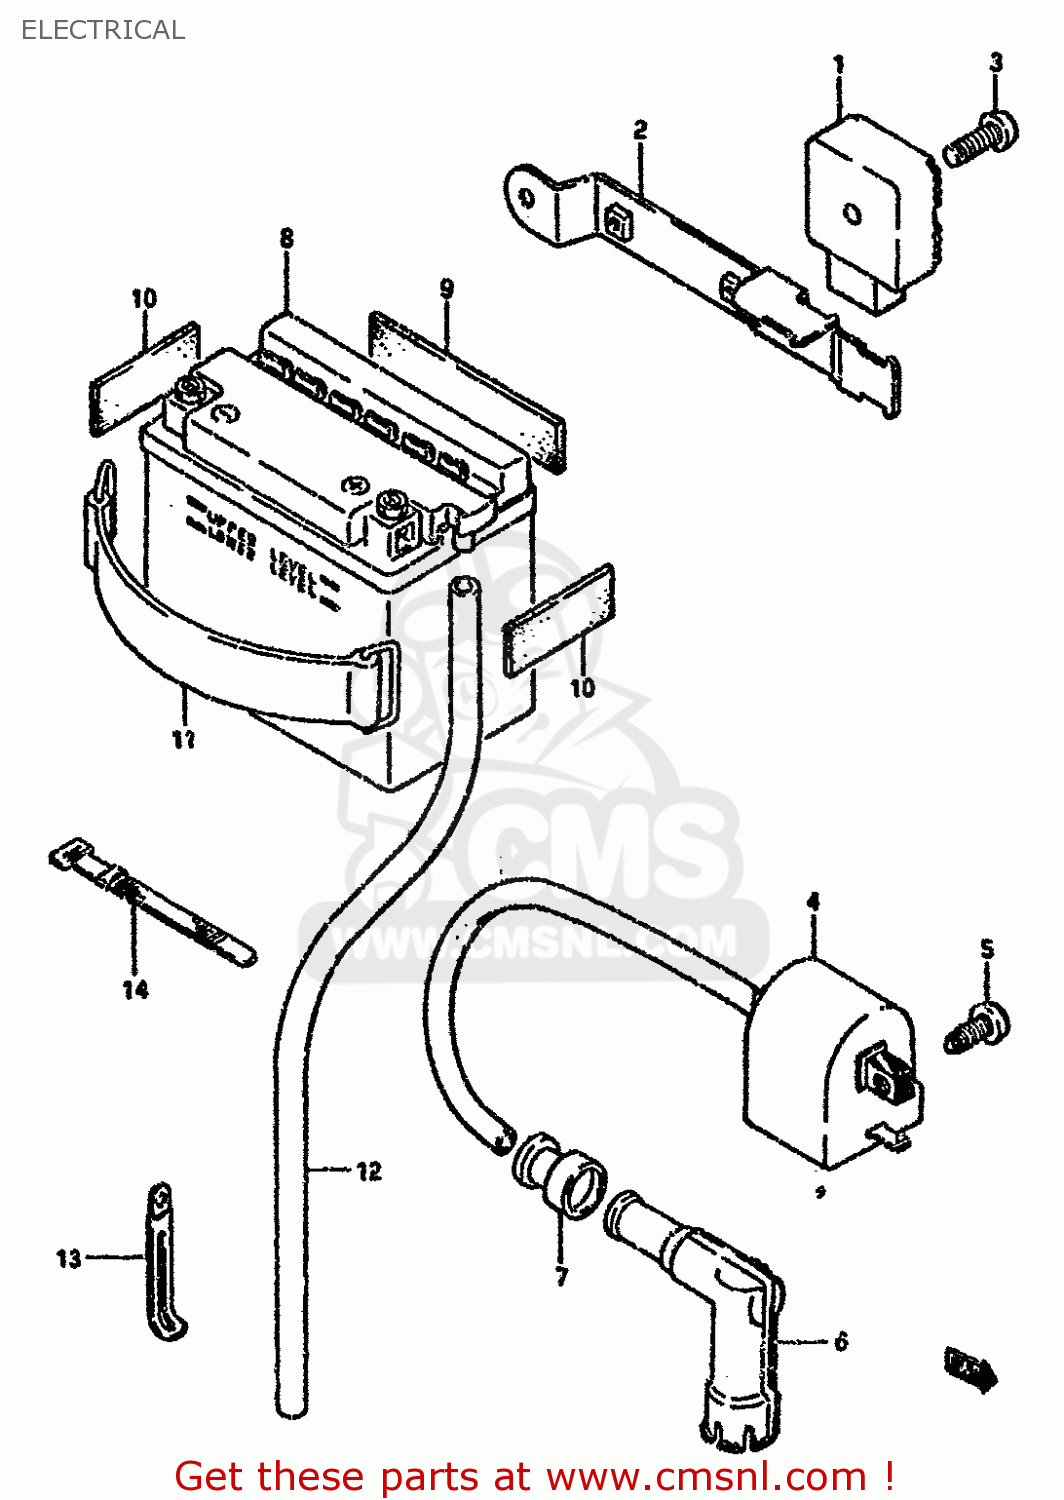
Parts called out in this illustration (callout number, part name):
1	RECTIFIER ASSY,REGULATOR
2	BRACKET
3	SCREW
4	UNIT/COIL ASSY,IGNITION
5	SCREW(6X21)
6	CAP,SPARK PLUG
7	SEAL,HIGH TENSION CORD
8	BATTERY ASSY(YB4L-B,12V4.2AH)
9	PROTECTOR(170X95X3.0)
10	PROTECTOR(170X95X3.0)
11	BAND
12	HOSE,BATTERY EXHAUST(L:780)
13	CLAMP
14	CLAMP
